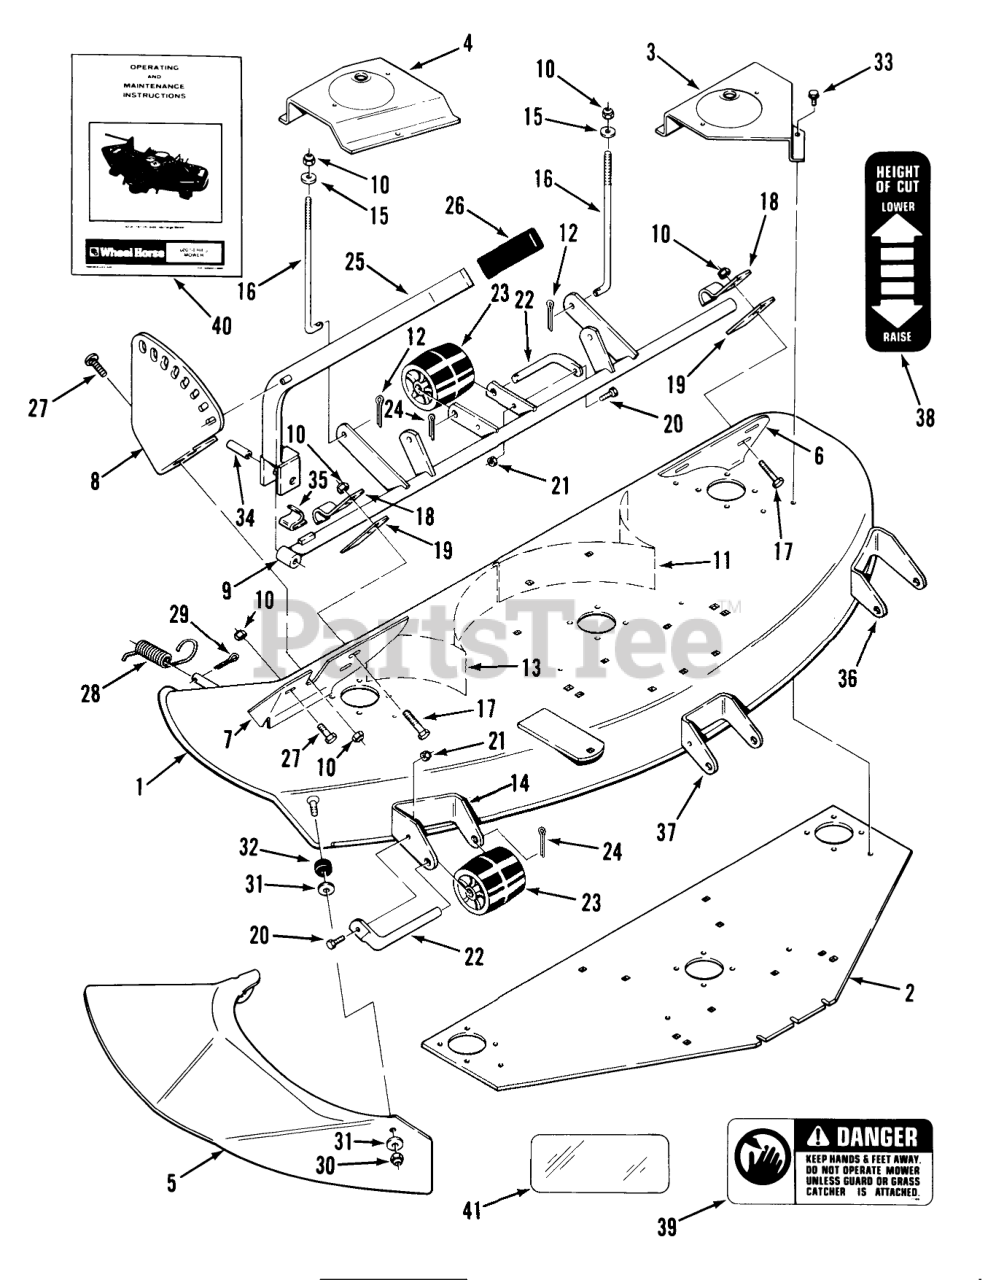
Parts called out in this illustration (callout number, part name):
1	Mower Deck
2	PLATE-DECK REINFO R
3	Belt Cover LH
4	Belt Cover RH
5	Chute Extension
6	PLATE-WEAR L.H. R
7	PLATE-WEAR R.H. R
8	Quadrant
9	WLDMT-LIFT ASS'Y R
10	NUT
11	BAFFLE-DECK LH
12	Hairpin
13	BAFFLE-DECK RH
14	BRKT-ROLLER R
15	Washer
16	ROD-LEVELER
17	Carriage Bolt
18	Clamp
19	Bar
20	Bolt
21	Nut
22	ROLLER-SHAFT
23	Roller
24	Cotter Pin
25	Lever
27	Bolt
28	Spring
29	Pop Rivet
30	Nut
31	Washer
32	BUSHING-PIVOT
33	Bolt
34	SPIROL PIN 3/8X1 1/2
35	CLIP-SPRING
36	BRKT-ROLER R
37	BRKT-ROLLER
38	DECAL-HOC
39	Danger Decal
40	Operator-s Manual
41	DECAL-OVERLAY
